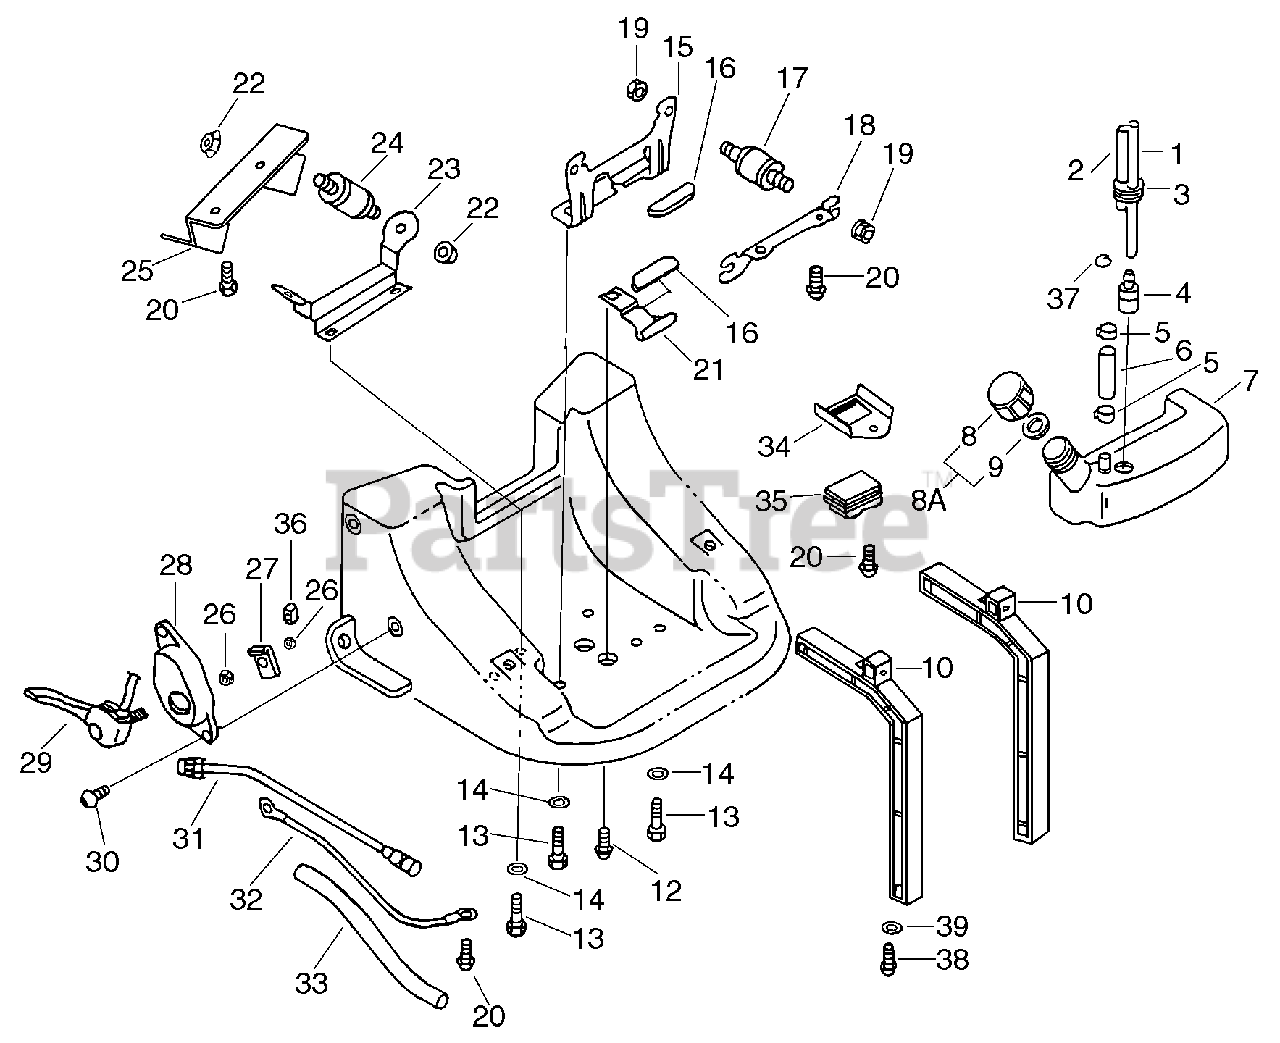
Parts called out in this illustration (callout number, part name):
1	PIPE - 3X6X200 -- BLACK
2	PIPE - FUEL
3	GROMMET
4	FILTER, FUEL
6	PIPE - FUEL
7	TANK, FUEL
8A	CAP ASSY
9	GASKET, CAP
10	FRAME, BACKPACK
12	SCREW - 6X15
13	BOLT - 6X16
15	BRACKET, TANK
16	CUSHION, TANK
18	BRACKET, ENGINE
19	NUT - 5 -- FLANGE
20	SCREW - 5X12
21	BRACKET, TANK
22	NUT - 6 -- FLANGE
23	PLATE, ANGLE
25	PLATE, ANGLE
27	PLATE, LIMITER
28	BRACKET, THROTTLE
29	CONTROL, THROTTLE
30	SCREW - 5X20
31	SWITCH, IGNITION
32	LEAD - GROUND
33	TUBE, PROTECTIVE
34	PLATE, ANGLE
37	CLIP - 6.5
